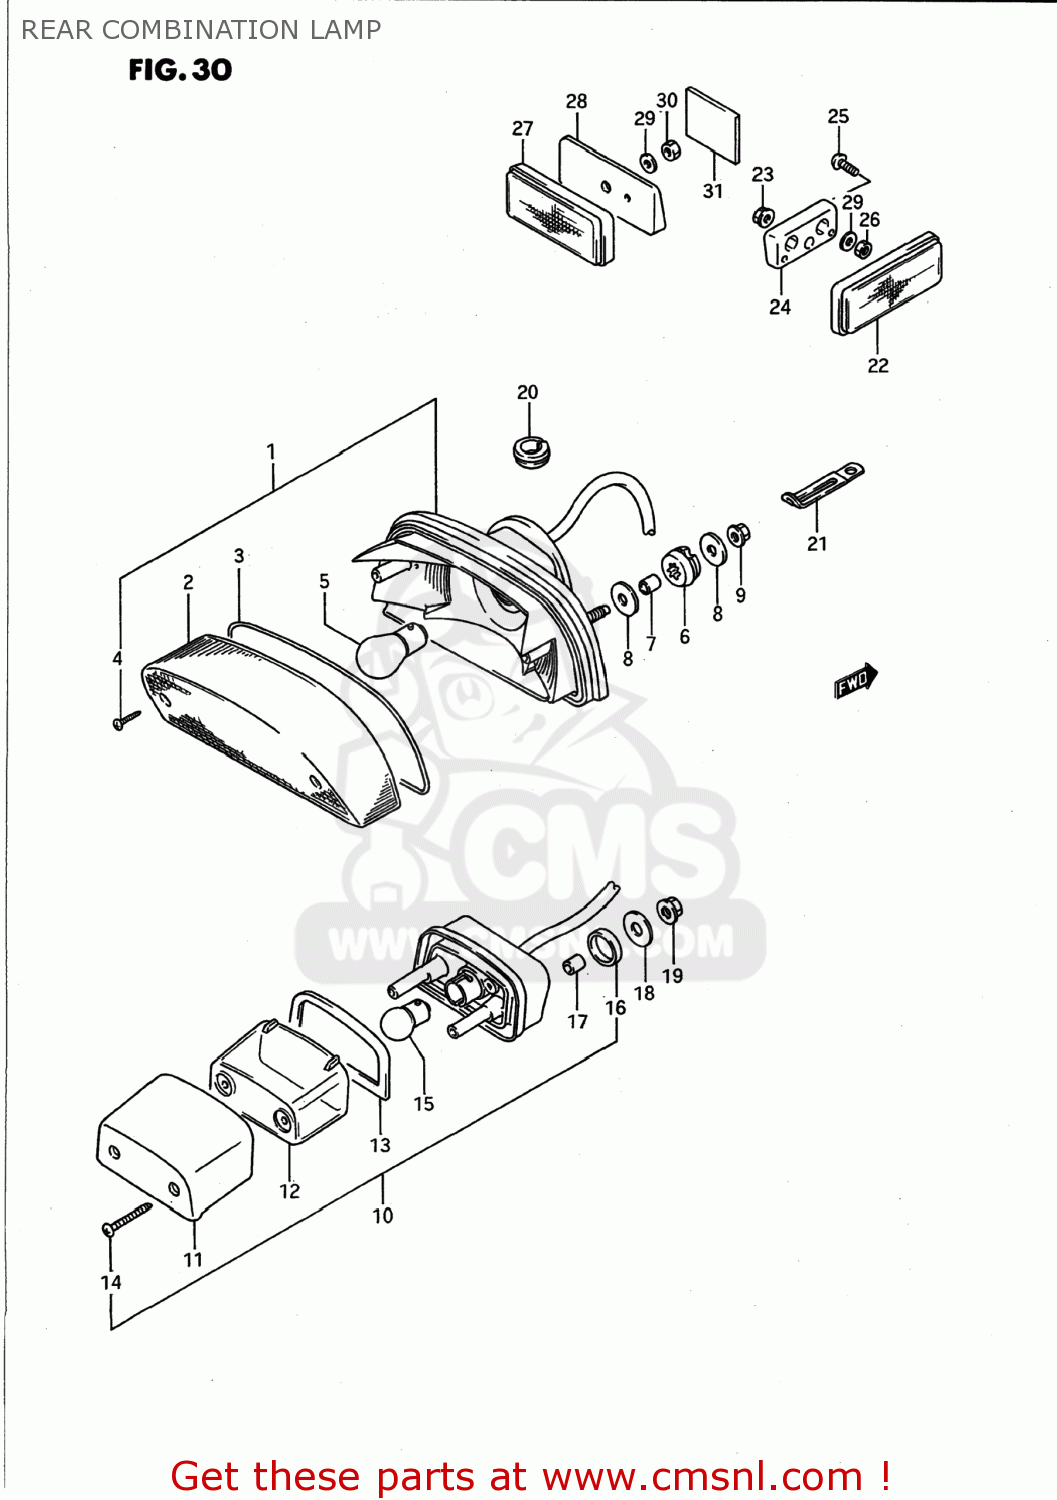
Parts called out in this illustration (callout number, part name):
1	LAMP ASSY,RR COMBINATION
2	LENS
3	GASKET (NAS)
4	SCREW
5	BULB(12V27/8W)
6	CUSHION
7	SPACER (6.4X9X10.5)
8	WASHER
9	NUT
10	LAMP ASSY,LICENSE
11	COVER,LICENSE LAMP
12	LENS,LICENSE LAMP
13	GASKET,LICENSE LAMP (NAS)
14	SCREW
15	BULB(12V7.5W)
16	CUSHION
17	SPACER
18	WASHER
19	NUT
20	GROMMET
21	CLAMP(L:45)
22	REFLEX REFLECTOR ASSY,RR
23	NUT
24	SPACER
25	SCREW 5X12
26	NUT
27	REFLEX REFLECTOR ASSY,RR
28	SPACER
29	WASHER
30	NUT
31	COVER,HARNESS
